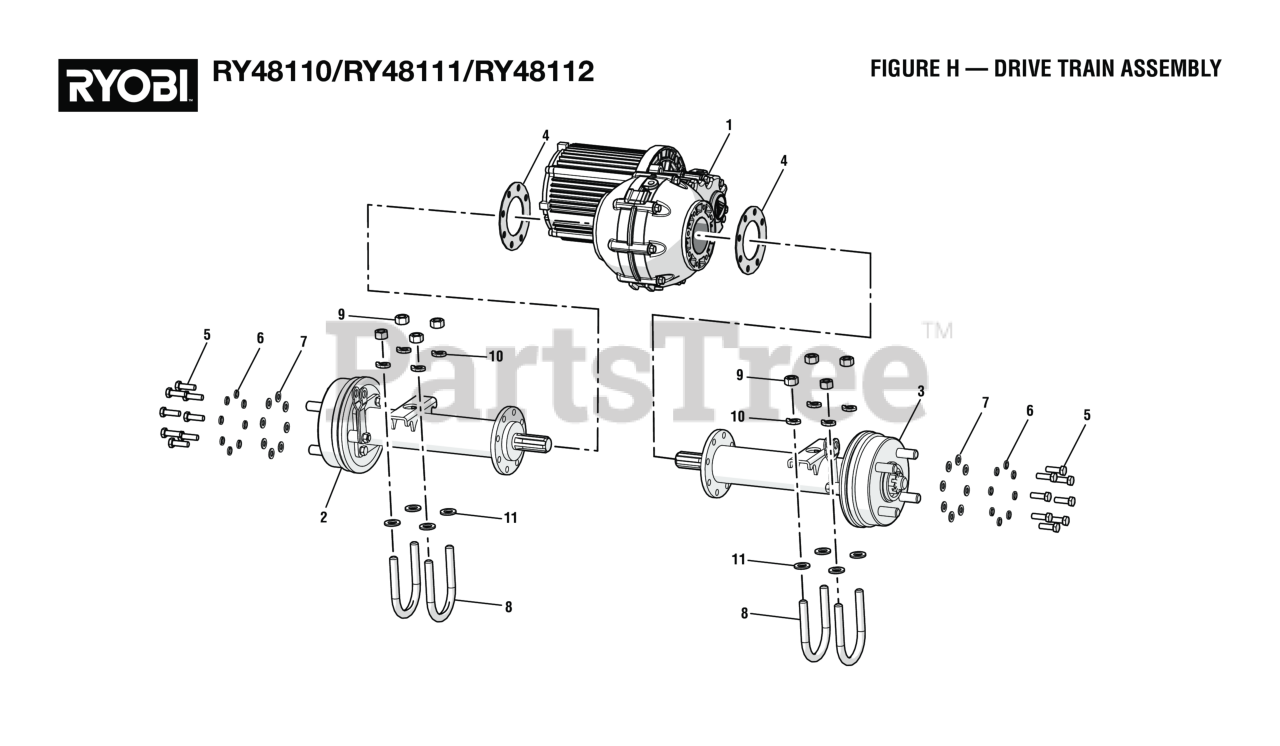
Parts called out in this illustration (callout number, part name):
1	Transaxle
2	Left Rear Axle
3	Right Rear Axle
4	Transmission Gasket
5	Bolt (M8 x 25 mm, Hex Hd.)
6	Lock Washer (OD9.8 x ID8.5 x 5t)
7	Washer (OD16 x ID8.4 x 1.6t)
9	Hex Nut (M12 x 1.75 mm)
10	Spring Washer (OD20 x ID12.4 x 2t)
11	Washer (OD24 x ID13 x 2.5t)
